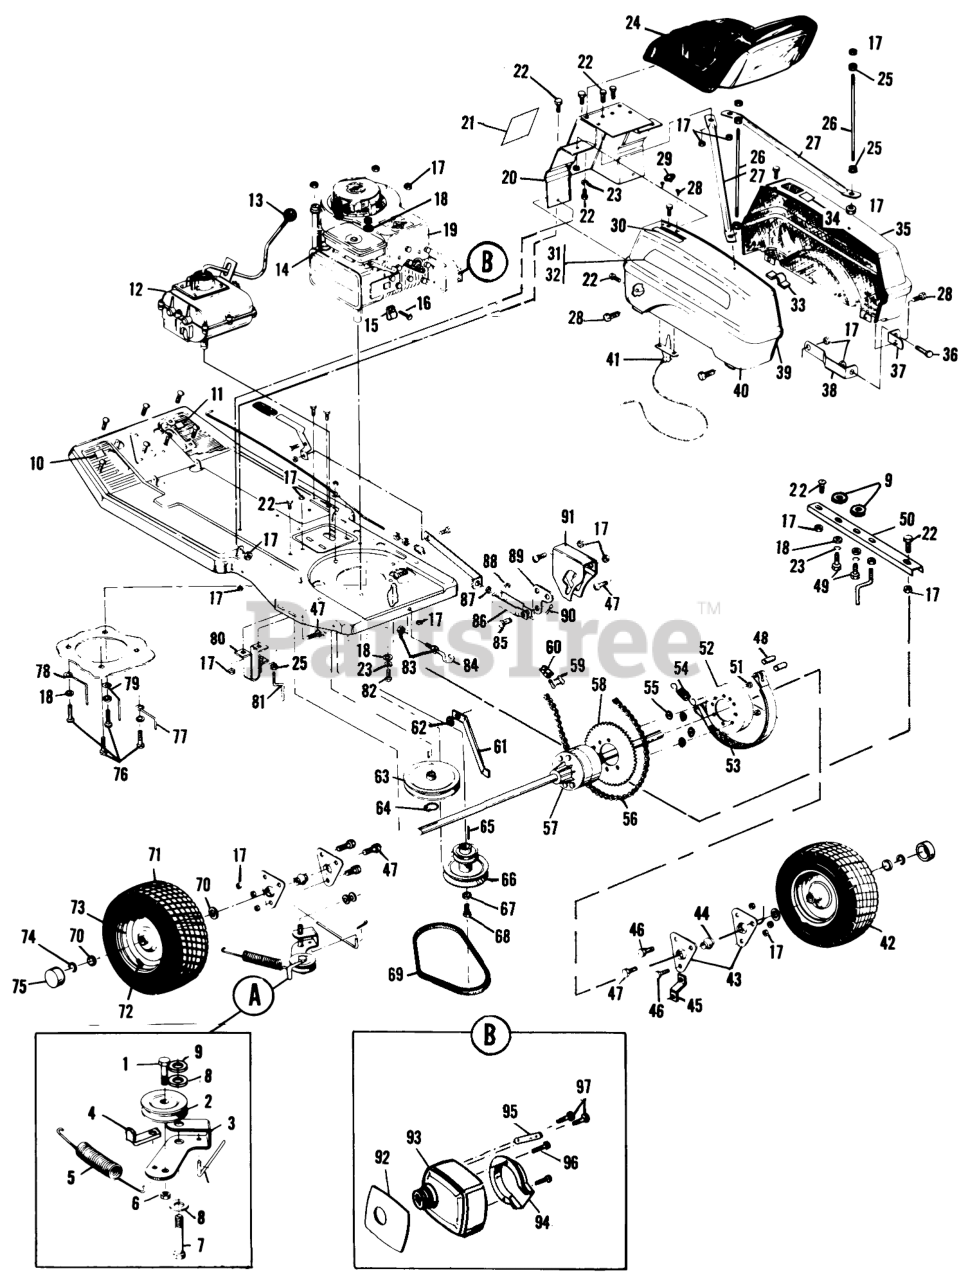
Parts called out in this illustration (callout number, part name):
1	Screw-Cap, Hex. Hd.
2	Idler Pulley
3	Idler Arm
4	Arm, Idler
5	Spring, Brake
6	Nut
7	Shoulder Bolt
8	Washer
9	Washer
10	Decal, Clutch
11	Decal, Brake
12	Transmission, 3-Speed (See Separate List Page 10)
14	Gas Gauge
15	Clip, Throttle Cable
16	Screw, Hex Hd, No.10-32 x 5/8 In.
17	Nut-Nylok
18	Washer
19	Engine
20	Support, Seat
21	Decal, Instruction
22	Bolt Hex 5/16-18
23	Lockwasher
25	Nut 5/16-18 Keps
26	Rod, Fender Reinforcing, L.H.
27	Strut, Seat Support
28	Screw, Taptite, 1/4-20 x 5/8 In.
29	Knob, Throttle Control
30	Decal, Throttle
31	Decal, Body, R.H.
32	Decal, Body, L.H.
33	Press Clip
34	Decal, Shift Pattern
35	Fender, Right
36	Hex Cap Screw
37	Bracket, Chain Adjust
38	Strap, Chain Adjust
39	Edging
40	Fender, Left
41	Control, Throttle
42	Wheel & Tire Assembly
43	Plate, Bearing Retainer
44	Bearing, Rear Axle
45	Retainer, Brake Band
46	Bolt 5/16-18 x 5/8 Carriage
47	Bolt-3/8-16 x 3/4
48	SPIROL PIN 3/8X1 3/4
49	Bolt 5/16-18 x 1
50	Channel Stiffner
51	Locknut, Hex, 5/16-18 Thd
52	Drum, Brake
53	Brake Band Assembly
54	Brake Return Spring
55	Spacer
56	Chain Assy (With Link)
57	Differential (See Separate List Page 3)
58	Sprocket, 40 Tooth (Differential Part)
59	Connector Link (Only)
60	Link, Offset
61	Belt Guide
62	Nut-Nylok
63	Bracket-Link
64	Snap Ring
65	Key, Square, 1/4 X 1/4 X 1 1/2 In.
66	Pulley, Engine
67	Lockwasher, Split, 3/8 In.
68	Screw, Hex Hd, 3/8-24 x 1 In.
69	"V" Belt, 4241
70	Flatwasher
71	Tire, 4.10-3.50 x 6
72	Valve Stem
73	Wheel
74	"E" Ring
75	Hub Cap
76	Bolt 5/16-18 x 1/2
77	Belt Guide
78	Belt Guide
79	Belt Guide
80	Bracket, Clutch Spring Assy
81	Belt Guide
82	Screw, Hex Hd, 5/16-18 x 3/4 In.
83	Nut
84	Eyebolt, Trailer Hitch
86	Clevis
87	Nut 1/4-20 Keps
88	Nut
89	Brake Lever
90	Cotter Key
91	Brake Cam Plate Assy
92	Heat Shield (Engine Part)
93	Muffler, Lo-Tone
94	Deflector, Muffler
95	Lock Strip, Muffler Mounting
96	Screw
97	Screw
